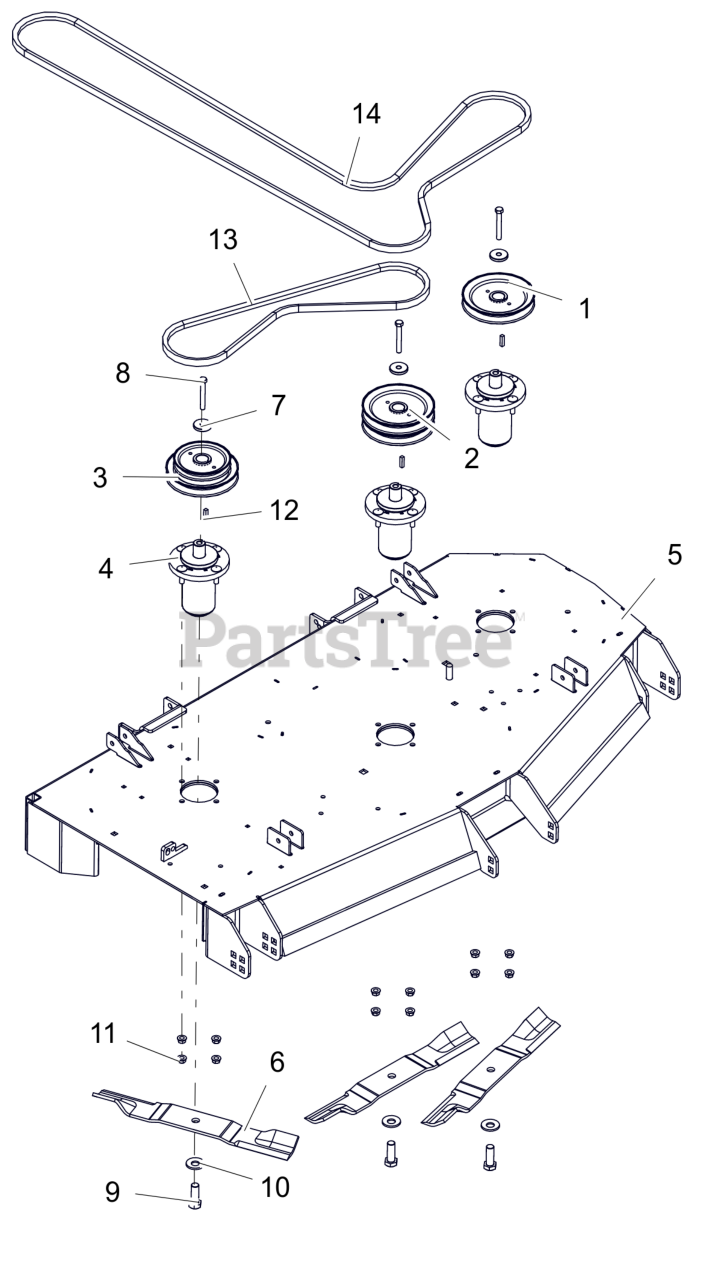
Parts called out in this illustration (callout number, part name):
1	PULLEY, SINGLE -1.000 ID X 6.000 OD
2	PULLEY, DOUBLE 1.000 ID X 6.000 OD
3	PULLEY, DBL-1"IDX6.00"&4.75"OD
4	ASM, MAINT FREE ALUM SPINDLE
5	WLDMT, 52" SIDE DISCH DECK X3 (RED) W/ SAFETY DECALS
6	BLADE, 18.00" MOWER (HI-LIFT)
7	RETAINER, SHEAVE
8	BLT, HEX .38-16X2.75 G8 ZCC
9	BLT, HEX .62-18X1.75 G8 ZCC
10	WSHR-BLVL .669X1.535X.138
11	NUT-LK-CTR-FLG .375-16 GF ZCC
12	KEY, SQ .25X.25X1.00 RC 40-50
13	V-BELT, B-COGGED
14	V-BELT, B SECTION
